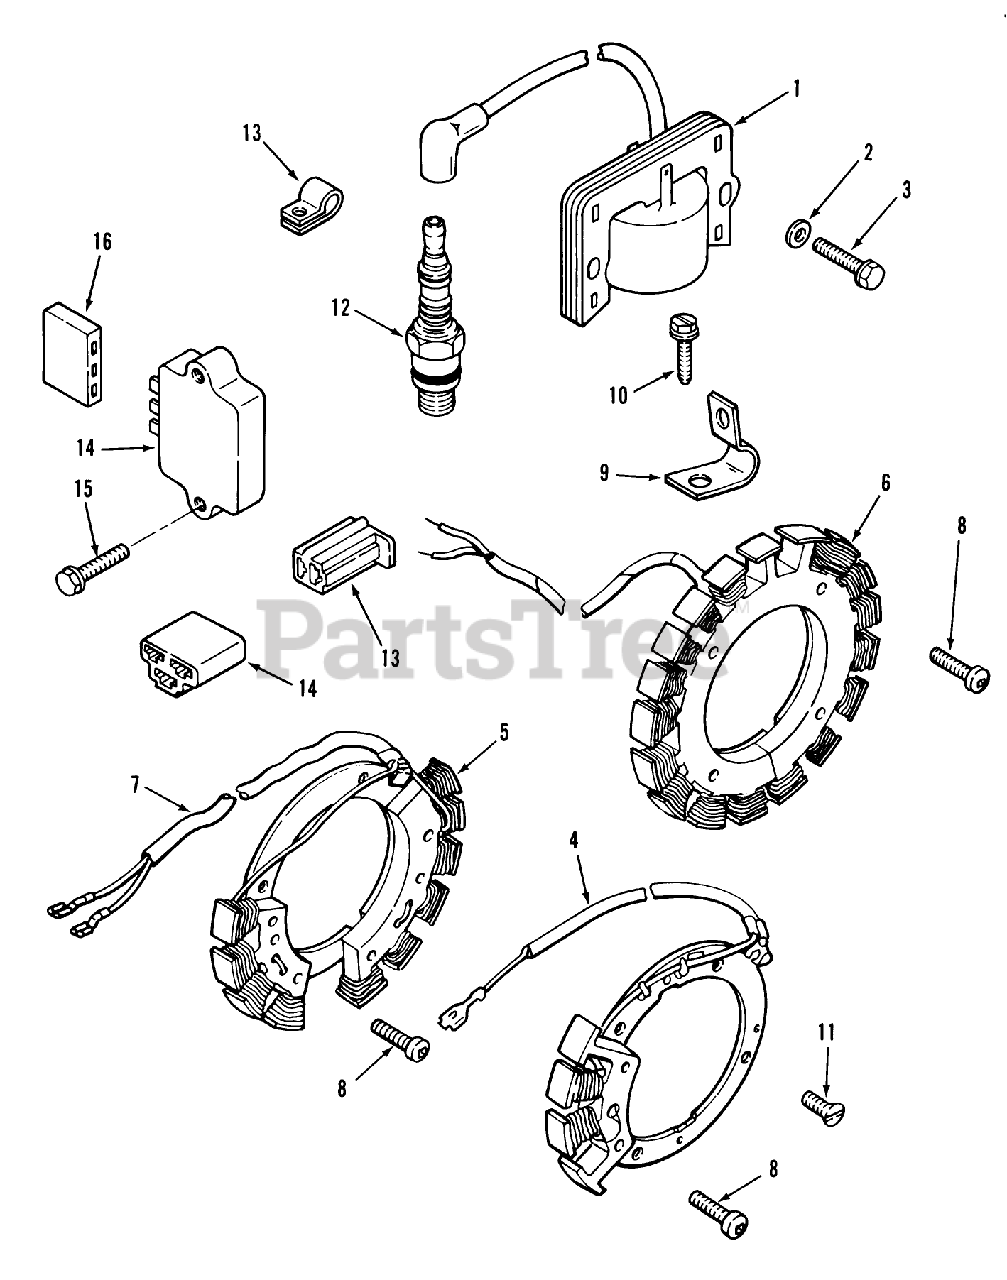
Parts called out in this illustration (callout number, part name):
1	KOHLER 41-584-02
2	KOHLER X-25-79
3	KOHLER X-156-1
4	KOHLER 25-085-03
5	KOHLER 45-085-02
6	KOHLER 237878
7	KOHLER 51-755-01
8	KOHLER X-67-51
9	KOHLER 210281
10	Hex. Wash. Hd. Screw 8-32 x 3/8
11	KOHLER X-131-1
13	KOHLER 210281
14	KOHLER 41-403-05
15	KOHLER X-132-4
16	KOHLER 236602
